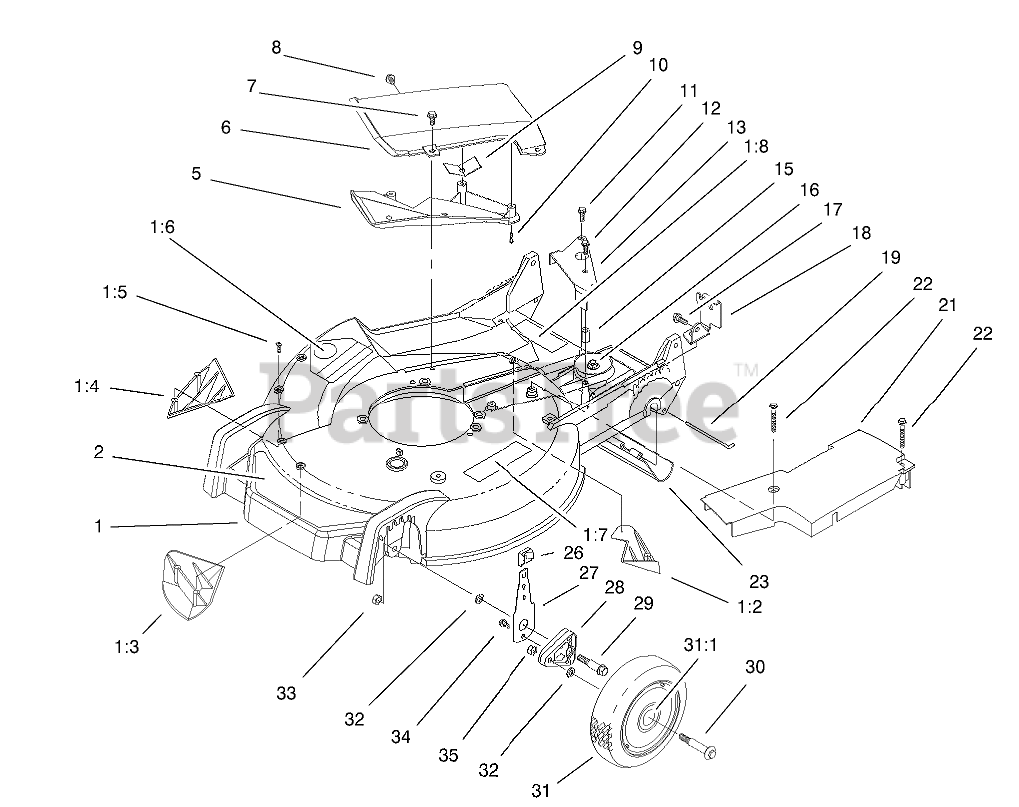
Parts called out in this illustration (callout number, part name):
1	HOUSING
1:2	KICKER-REAR
1:3	KICKER-FRONT
1:4	KICKER-RH
1:5	SCREW-PPH
1:6	DECAL-DANGER
1:7	DECAL-WARNING
1:8	DECAL-WARNING
2	DECAL - DECK
5	Deflector (Only On: 20042)
6	Cover (Only On: 20042)
7	Screw & Washer ASM (Only On: 20042)
8	Screw & Washer ASM (Only On: 20042)
9	Cover Guard (Only On: 20042)
10	Screw-PPH (Only On: 20042)
11	SCREW-HWHTF
12	SCREW-HWHTF
13	BRACKET-TRANSMISSION ACTUATOR
15	BUSHING-PLATE, ACTUATOR
16	ASM-Gearcase
17	SCREW-HWHTF
18	BRACKET-CABLE, TRACTION
19	ROD-SHIELD
21	COVER-BELT
22	SCREW-HHFTF
23	SHIELD-TRAILING
26	KNOB-ARM
27	FRONT SPRING ARM ASM
28	ARM-PIVOT, FRONT
29	BOLT-SHOULDER
30	BOLT-SHOULDER
30	BOLT-WHEEL
31	WHEEL ASM
31	WHEEL AND TIRE ASM
31:1	BUSHING
32	WASHER
33	NUT-LOCK
34	SCREW-HWH
35	NUT-LOCK
